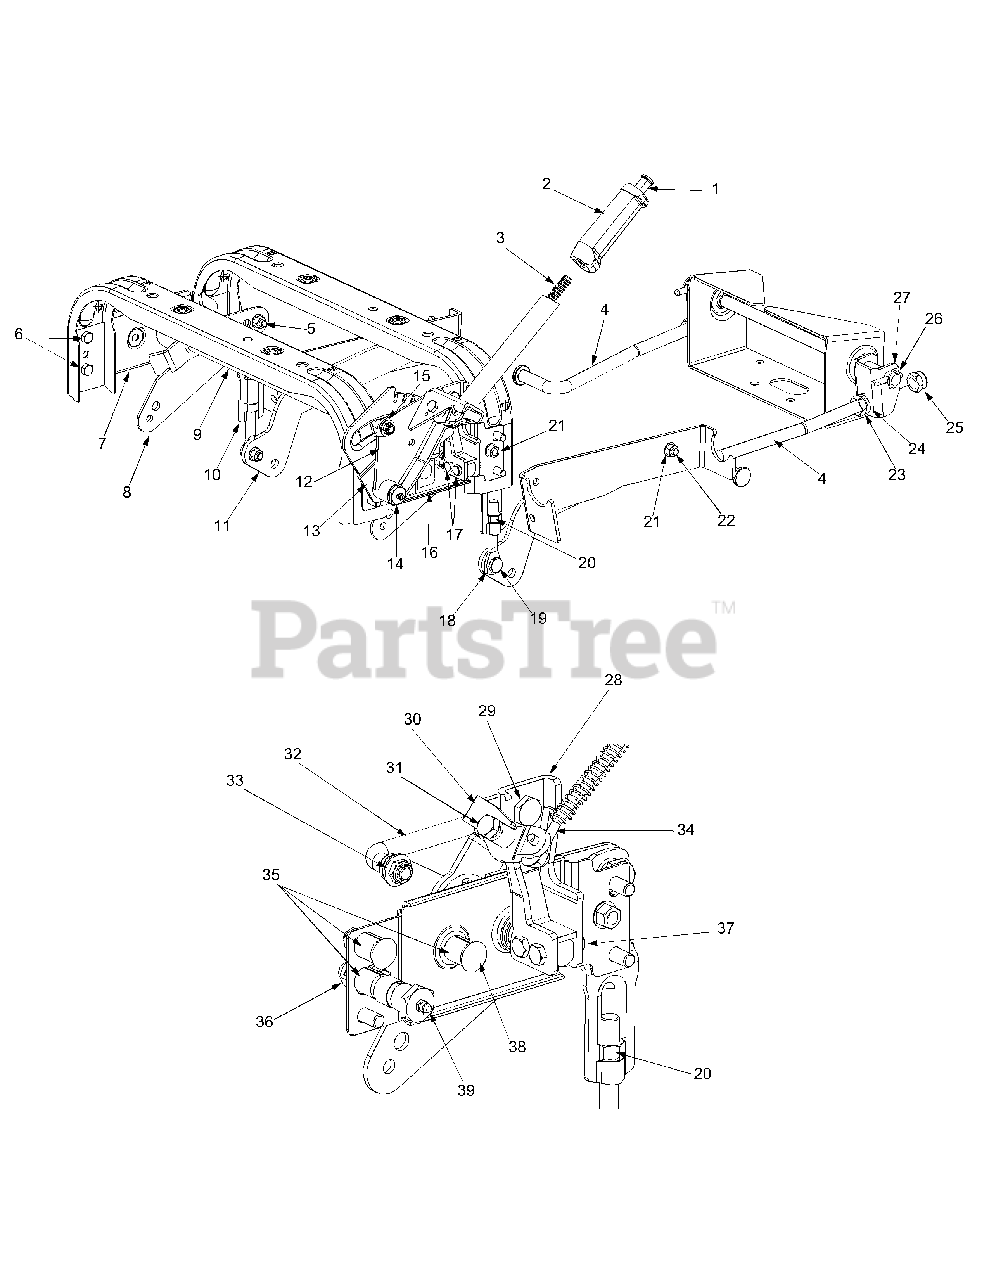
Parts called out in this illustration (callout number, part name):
1	Handle Button
2	Handle Deck Lift Grip
3	Compression Spring
4	Front Lift Rod
5	Shoulder Screw .500 Dia x .434
6	Hex Cap Screw 3/8-16 x .75
7	Shaft Mounting Bracket - LH
15	Top Lock Jam Nut 3/8-16
16	Shaft Mounting Bracket - RH
17	Hex Cap Screw 5/16-18 x 1.375
18	Eye Bolt Adjustable Link
19	Shoulder Screw 3/8-16
20	Hex Nut 1/2-13
21	Flange Lock Nut 3/8-16
22	Shoulder Screw 3/8-16 .56 x .27
23	Jam Nut 5/8-11
24	Lock Washer 5/8
25	Lock Hex Nut 5/8-11
31	Hex Cap Screw 3/8-16 x 2.25
32	Lift Link Rod
33	Flat Washer .406 x .875
35	Spacer .448 ID x .688 OD
36	Lock Nut 7/16-14
37	Hex Center L-Nut 5/16-18
38	Hex Screw 3/8-16 x 1.50
39	Grease Fitting
